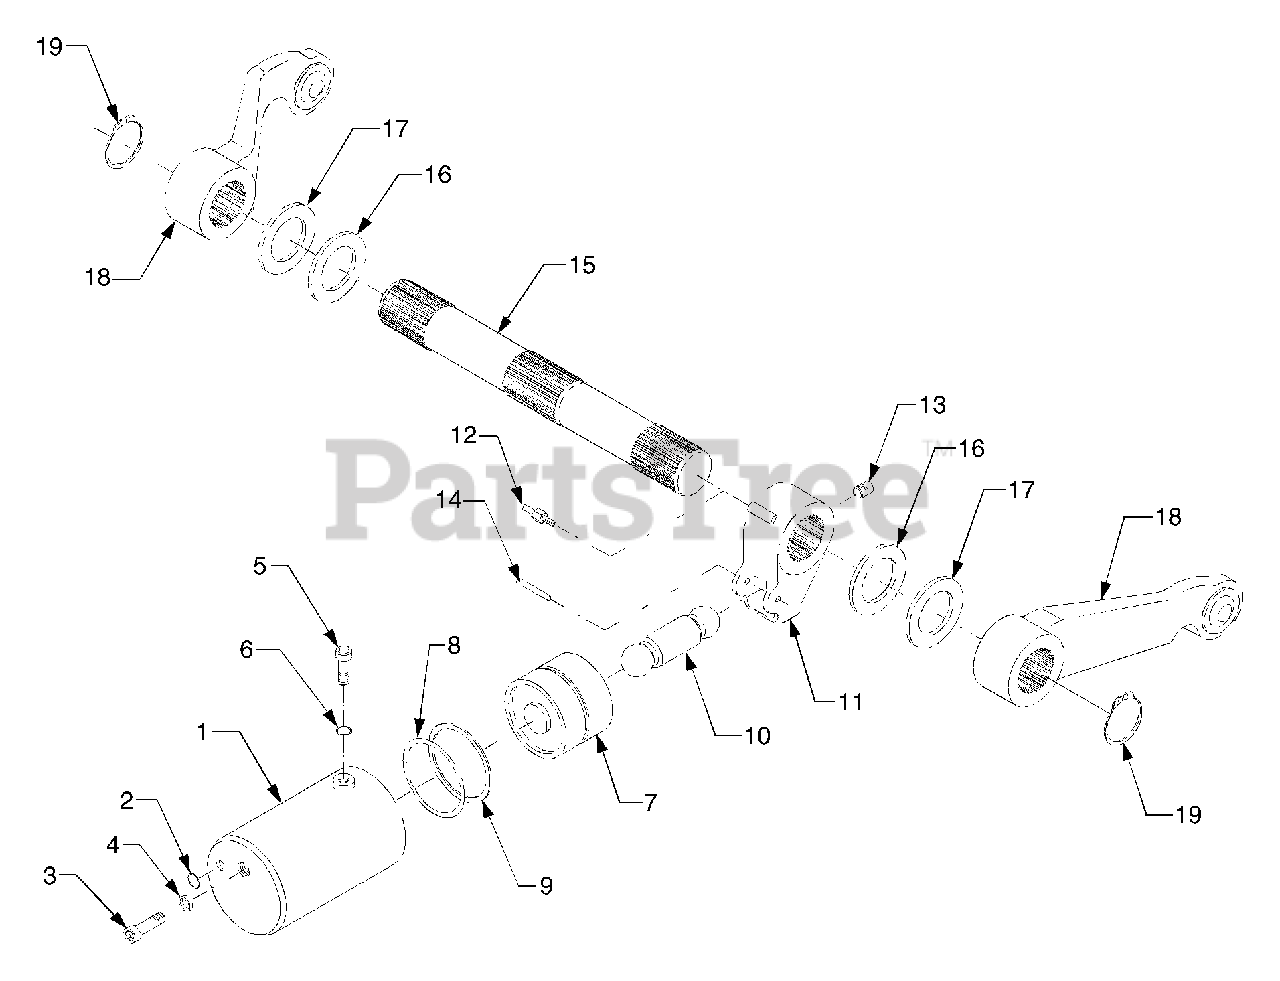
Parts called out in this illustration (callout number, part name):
10	Rod, Hydraulic
11	Arm, Hydraulic
15	Shaft, Hydraulic Arm
18	Lift Arm Ass'y
